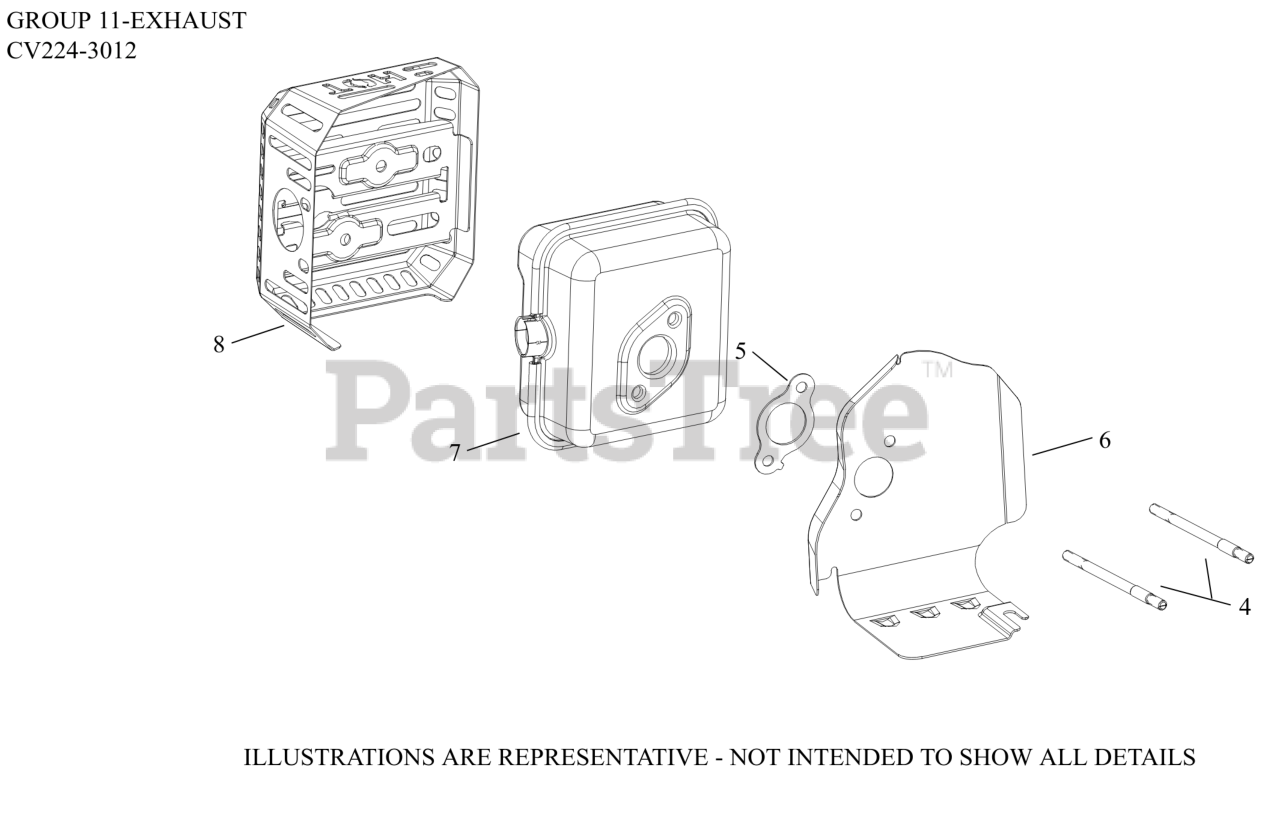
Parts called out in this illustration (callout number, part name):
4	STUD, EXHAUST (M6)
5	GASKET, MUFFLER (HEAT DEFLECTOR)
6	BAFFEL, BARREL
7	MUFFLER, ASSEMBLY
8	GUARD, MUFFLER ASSEMBLY
